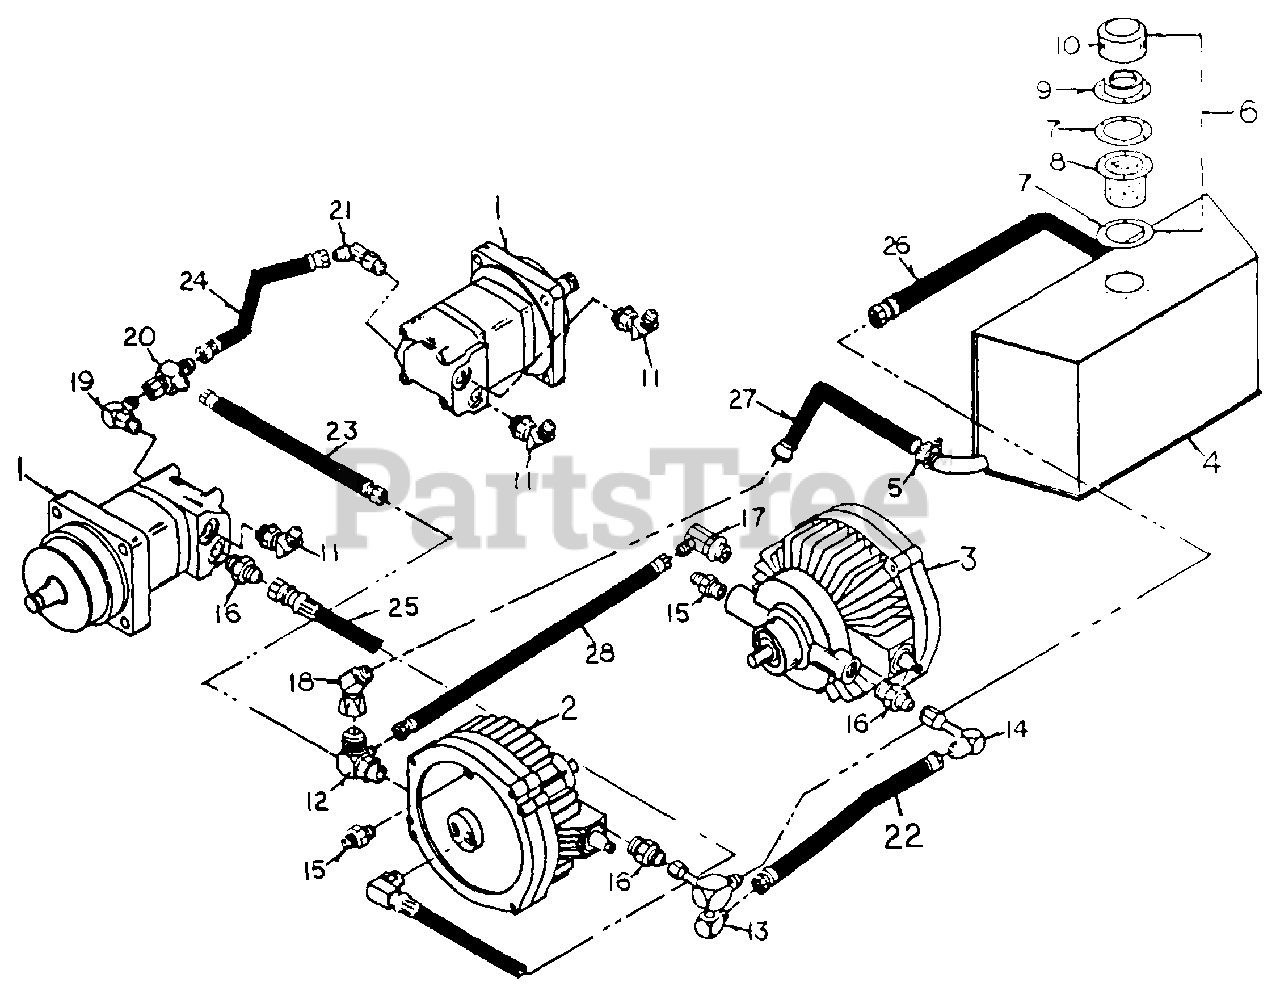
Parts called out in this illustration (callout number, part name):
3	Pump, RH
4	Hydraulic Oil Tank
5	Hose Clamp
6	Hydraulic Fill Cap Assembly
8	Strainer
9	Fill Neck
11	Male Tube, 45° O-ring Adapter
13	Special Adapter
14	Male Tube, 90° Female swivel Adapter
15	Male Tube, Male O-ring Adapter
16	Male Tube, Male O-ring Adapter
17	Male Tube, 90° Male O-ring Adapter
18	Male Tube, 45° Female Swivel Adapter
19	Male Tube, 90° Male O-ring Adapter
20	Male Tube, Female Swivel Tee
21	Male Tube, 45° Female Swivel Adapter
22	Hose, 1/2" ID x 18" Long, Easy Couple
23	Hose, 1/4" ID x 14" Long, Easy Couple
24	Hose, 1/4" ID x 20" Long, Easy Couple
25	Hose, 1/2" ID x 36 1/2" Long
26	Hose, 3/4" ID x 22" Long, Easy Couple
27	Hose, 3/4" ID x 18" Long, Easy Couple
28	Hose, 1/2" ID x 20" Long, Easy Couple
